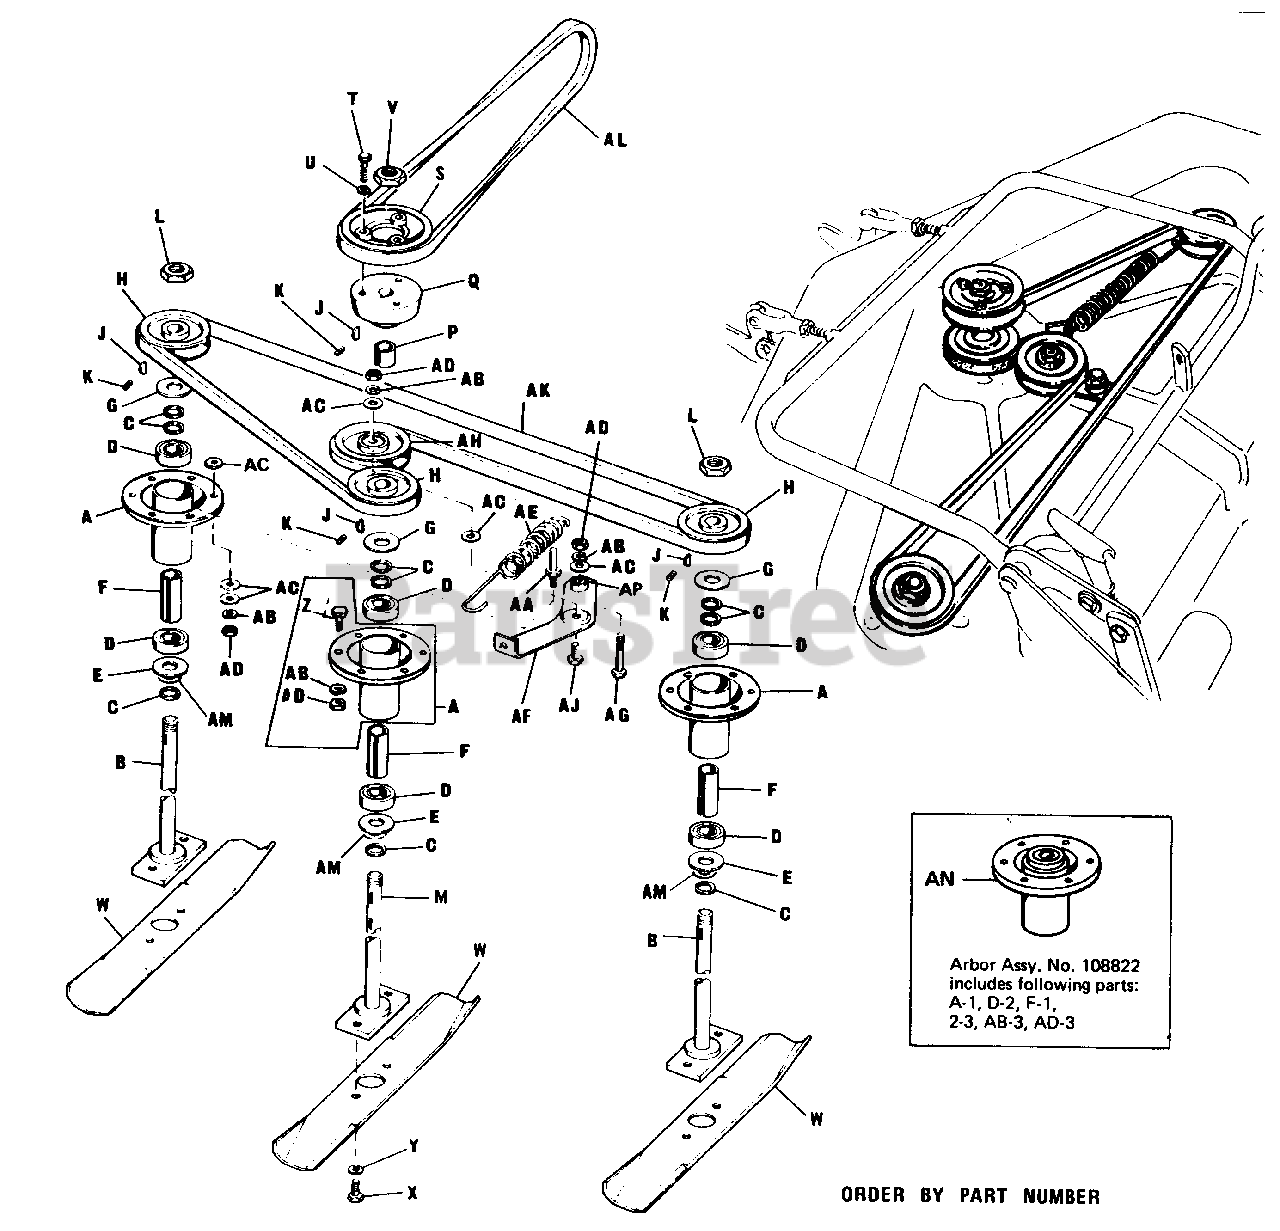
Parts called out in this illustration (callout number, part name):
A	Tube Assembly, Arbor
B	Arbor Assembly
J	Woodruff Key, // 61-3/16 x 5/8"
K	Set Screw, 5/16"-18 x 3/8"
L	Hex. Lock Nut, 3/4"-16
M	Arbor Drive Assembly
T	Hex. Cap Screw, 5/16-18 x 1-1/2"
U	Lock Washer, 5/16"
V	Hex. Lock Nut, 3/4"-16
W	Knife Blade
X	Hex. Cap Screw, 3/8"-16 x 5/8"
Y	Lock Washer, 3/8"
Z	Screw Hex. Cap, 3/8"-16 NC x 3/4" lg. Zinc or Cad. Pl.P.
AB	Lock Washer, 3/8"
AC	Plain Washer, 5/16 "
AD	Full Hex Nut, 3/8"-16
AE	Tension Spring
AF	Idler Lever Assembly
AG	Hex. Cap Screw, 3/8"-16 x 1-3/4"
AH	Idler Pulley
AL	BELT, A-Sect, 45.10
AN	Arbor Assembly with Bearings and Hardware
